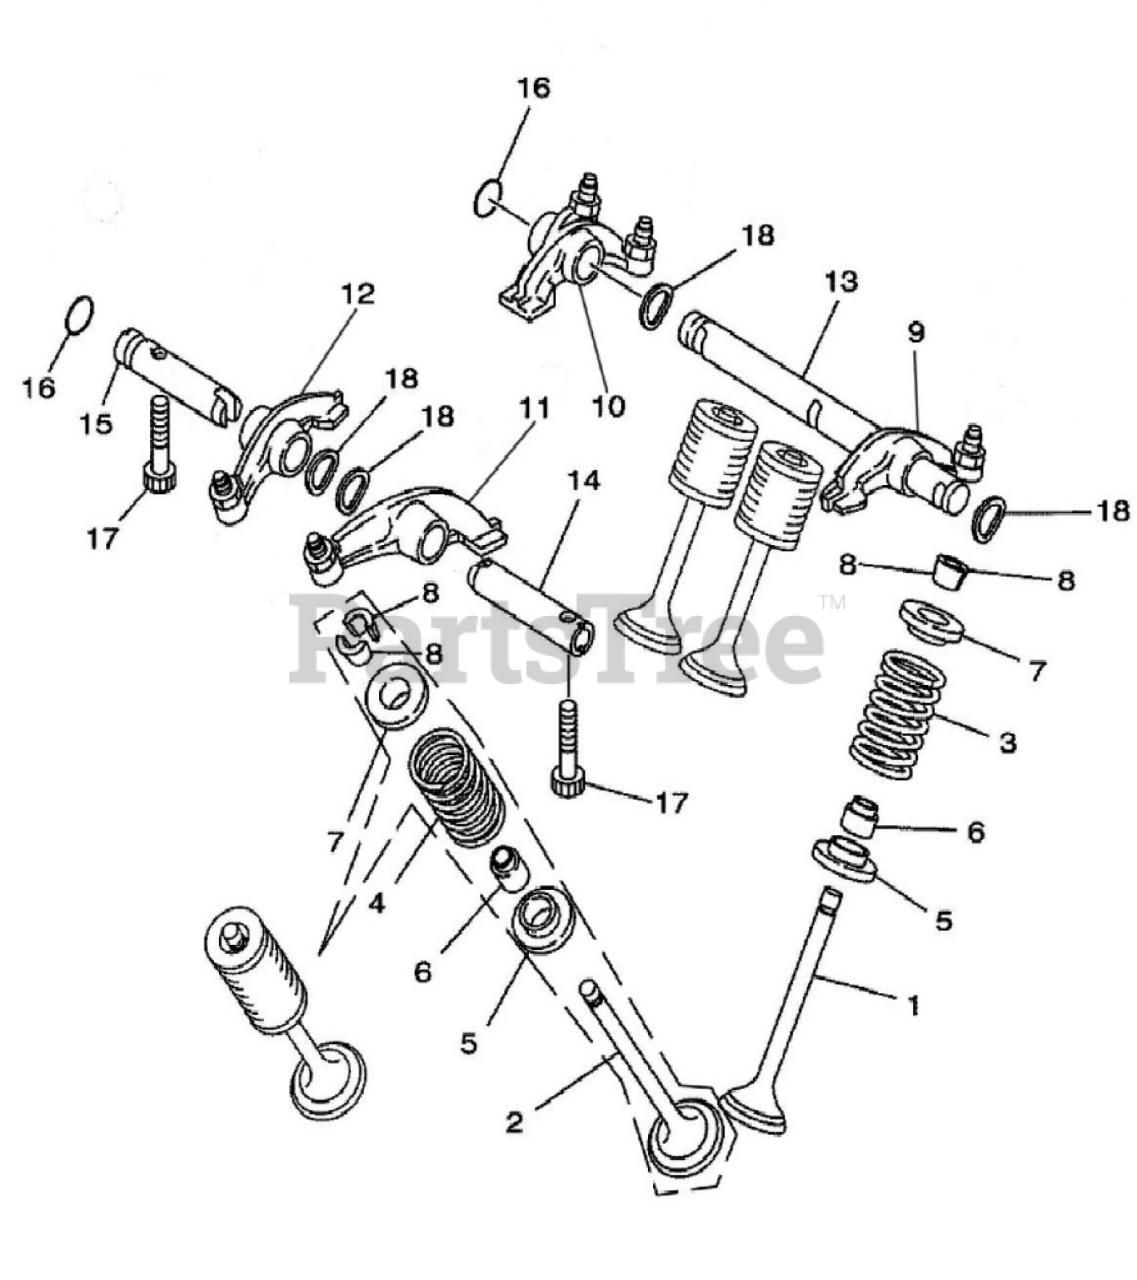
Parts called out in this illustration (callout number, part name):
1	Intake Valve
2	Exhaust Valve
3	Spring,Intake Valve
4	Spring,Exhaust Valve
5	Valve Spring Washer
6	Valve Stem Seal
7	Retainer,Valve Spring
8	Valve Lock Clamp
9	Intake Valve Rocker I?26?
10	Rocker Arm II?27?,Intake
11	Exhaust Valve Rocker II?29?
12	Exhaust Valve Rocker I?28?
13	Intake Valve Rockershaft
14	Exhaust Valve Rockershaft I
15	Exhaust Valve Rockershaft II
16	O-Ring 9x2
17	Hex head cap screw M6x20
18	Wave Mode Washer 12.5x34x0.4
